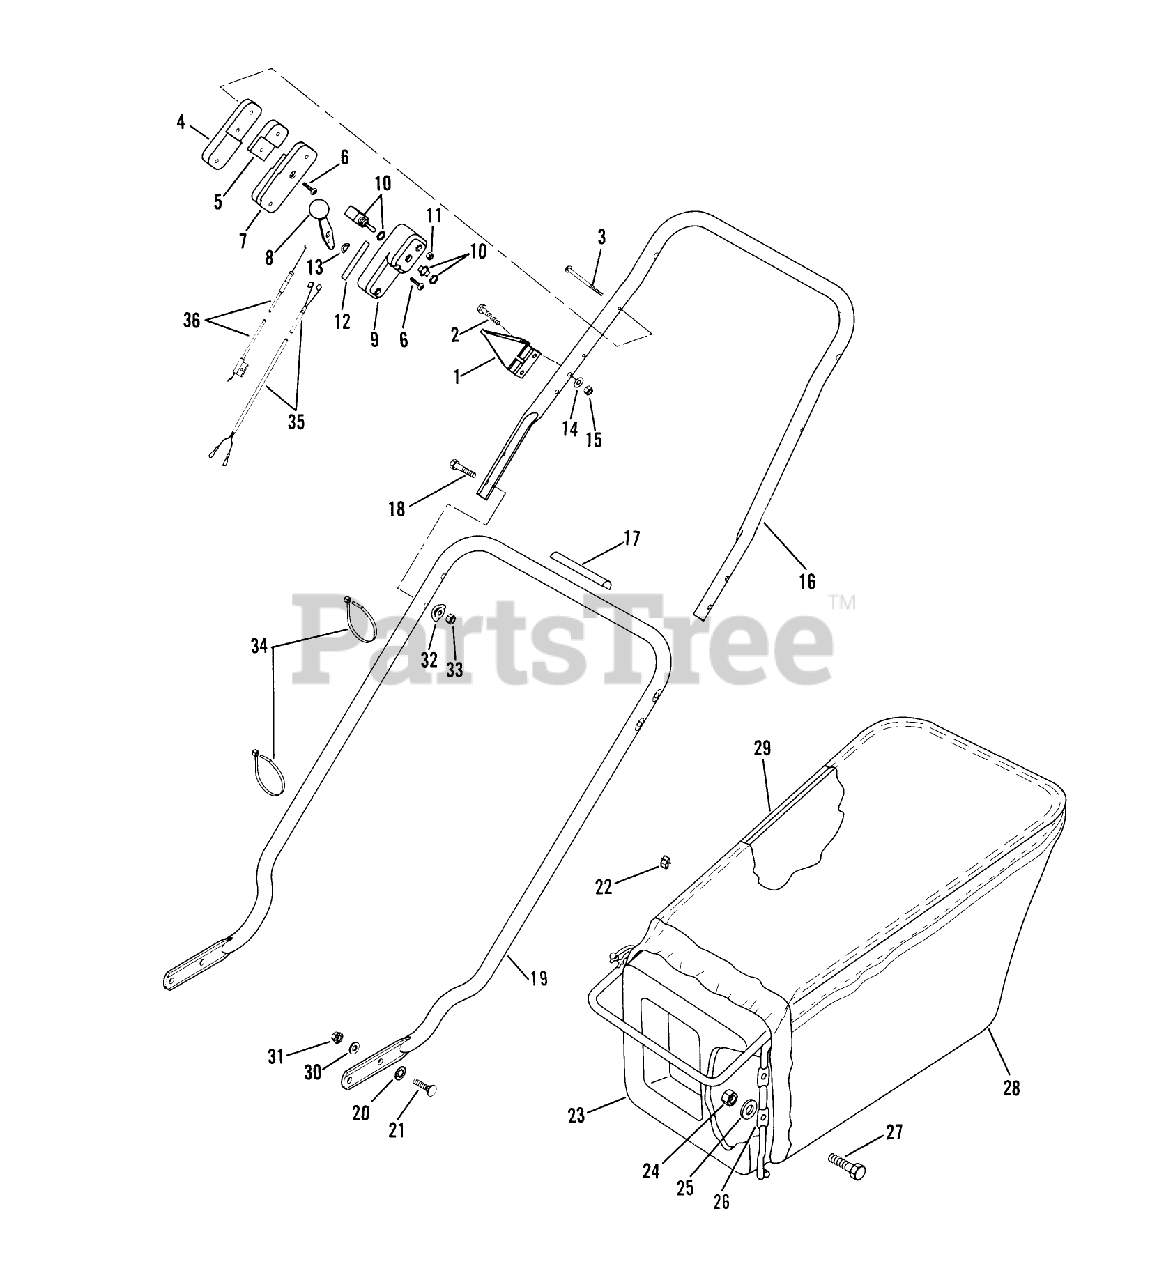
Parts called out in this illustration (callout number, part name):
3	SCREW
4	OUTER CONTROL CASE
6	SCREW
8	LEVER&KNOB AY WES
11	NUT C/LOCK E
13	WASHER-SPRING
14	LOCKNUT E
15	WASHER
16	UPPER HANDLE *
19	LOWER HANDLE *G
22	S CLIP ARDEN
23	BAG ADAPTOR PL
24	LOCKNUT E
25	WASHER
26	LATCH BAR AY ARGO
29	HANGER BAG TROX
30	WASHER
32	WASHER-CURVED
33	NUT-LOCK F
36	THROTTLE CABLE
